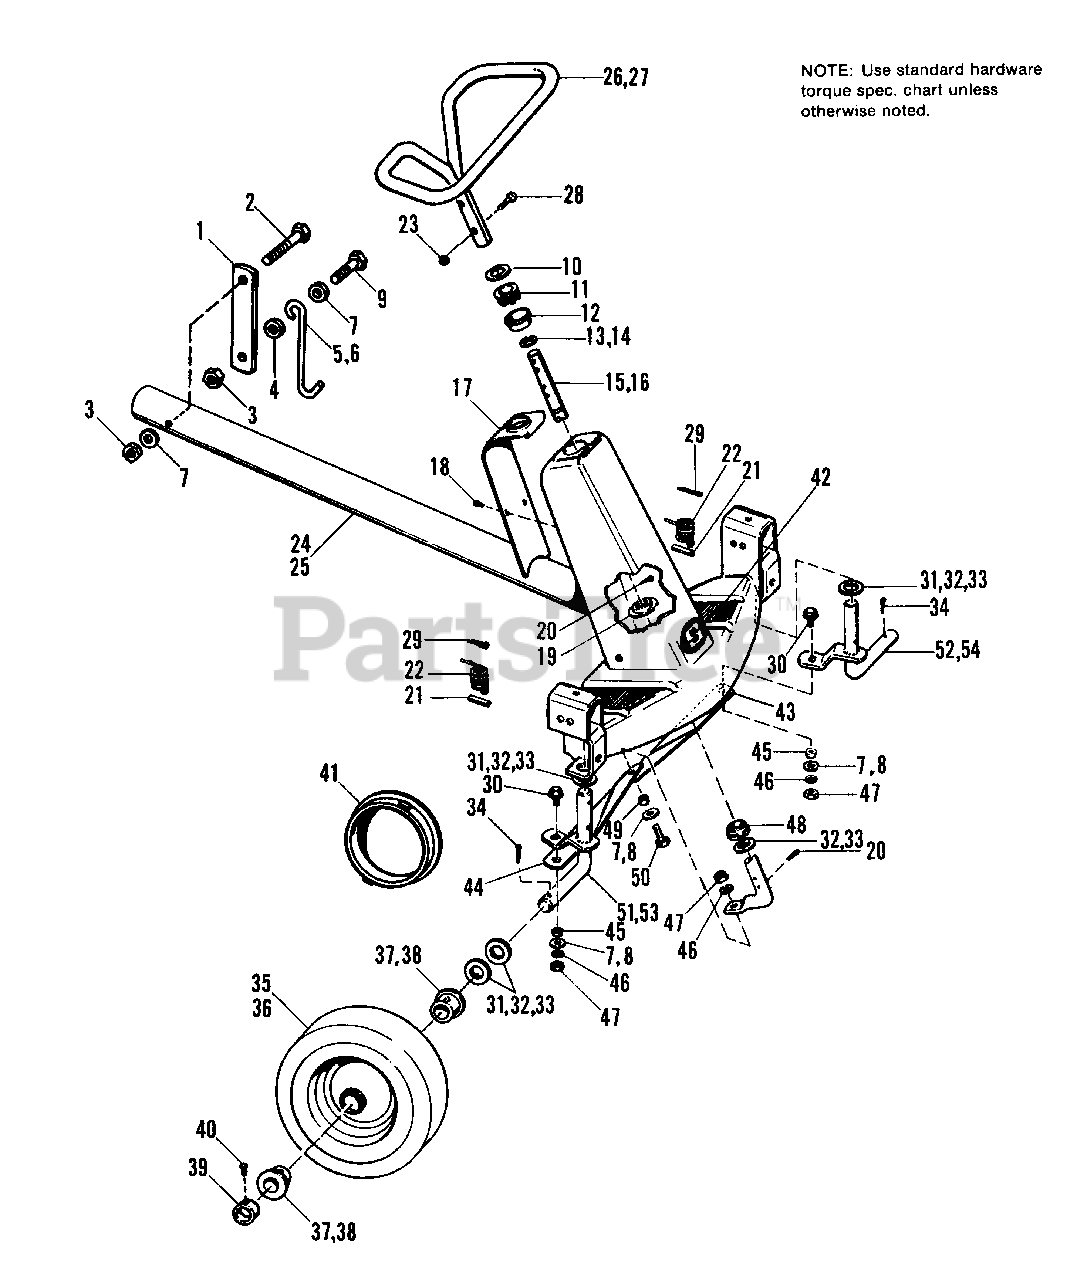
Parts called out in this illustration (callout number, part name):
1	BRACKET (170184 for 990614 Only)
2	CAPSCREW, Hex Hd., 3/8-16 x 3
3	LOCKNUT, Hex, 3/8-16
4	WASHER, Plastic, 3/8
5	LIFT
6	LIFT
7	WASHER, Plain, 3/8
8	WASHER, Plain, 3/8
9	CAPSCREW, Hex Hd., 3/8-16 x 1
11	BUSHING, Steering
12	CUP, Bushing, Steering
13	RING, Retaining
14	RING. Snap
15	HAFT, Steering
16	SHAFT, Steering
17	COVER, Steering Support
18	SCREW, Self Tapping, #10 x 3/8
19	CUP, Steering Shaft
20	PIN, Cotter, 5/32 x 1-1/4
21	PIN, Roll, 5/16 Dia. x 1-1/4
22	SPRING, Torsion
23	LOCKNUT, Hex, 5/16-18
24	FRAME & AXLE ASSY., Front
25	FRAME & AXLE ASSY, Front
26	HANDLE ASSY., Steering
27	HANDLE ASSY., Steering
28	CAPSCREW, Hex Hd., 5/16-18 x 1-1/4
29	PIN, Cotter, 5/32 x 1
30	SCREW, Hex, Whizlock, Flange, 3/8-16 x 1
31	WASHER
32	WASHER, (Used On 990390)
33	WASHER (Used On 990357)
34	PIN, Cotter, 3/16 x 1-1/4
35	WHEEL & TIRE ASSY., Front
36	WHEEL & TIRE ASSY., Front
37	BEARING, Relief (for service)
38	BEARING, Relief (for service)
39	COLLAR, Set
40	SETSCREW, Cup Pt., 5/16-18 x 5/16
41	HUB CAP, Front (Kit No. 990615)
42	PAD, Foot, L.H. & R.H.
43	LINK, Steering, L.H.
44	LINK, Steering, R.H.
46	LOCKWASHER, 3/8
47	NUT, Hex, Full, 3/8-16
50	CAPSCREW, Hex Hd., 3/8-16 x 1-1/2
51	SPINDLE ASSY., R.H.
52	SPINDLE ASSY., L.H.
53	SPINDLE ASSY., R.H.
54	SPINDLE ASSY., L.H.
